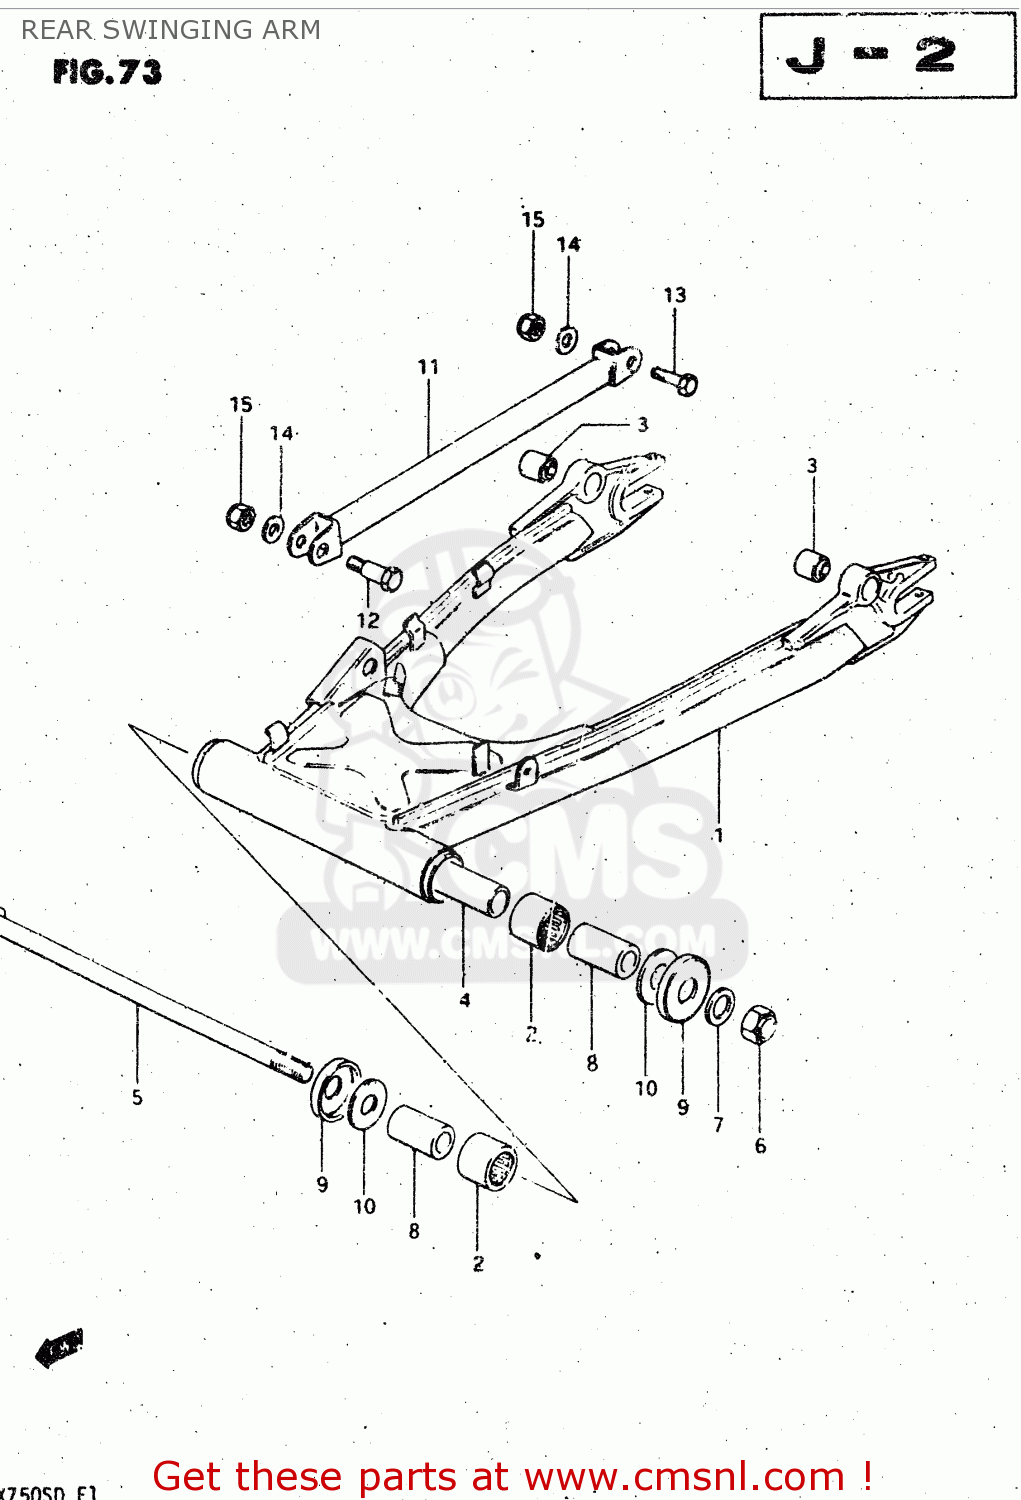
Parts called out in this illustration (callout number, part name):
1	SWING ARM ASSEMBLY,REAR
2	BEARING
3	BUSH
4	SPACER,RR SWGARM PIVOT CTR
5	SHAFT,REAR SWING ARM
6	NUT 16MM
7	WASHER
8	SPACER,RR SWGARM PIVOT
9	COVER,RR SWINGINGARM PIVOT
10	WASHER
11	LINK,RR TORQUE
12	BOLT
13	BOLT(10X39)
14	WASHER
15	NUT
